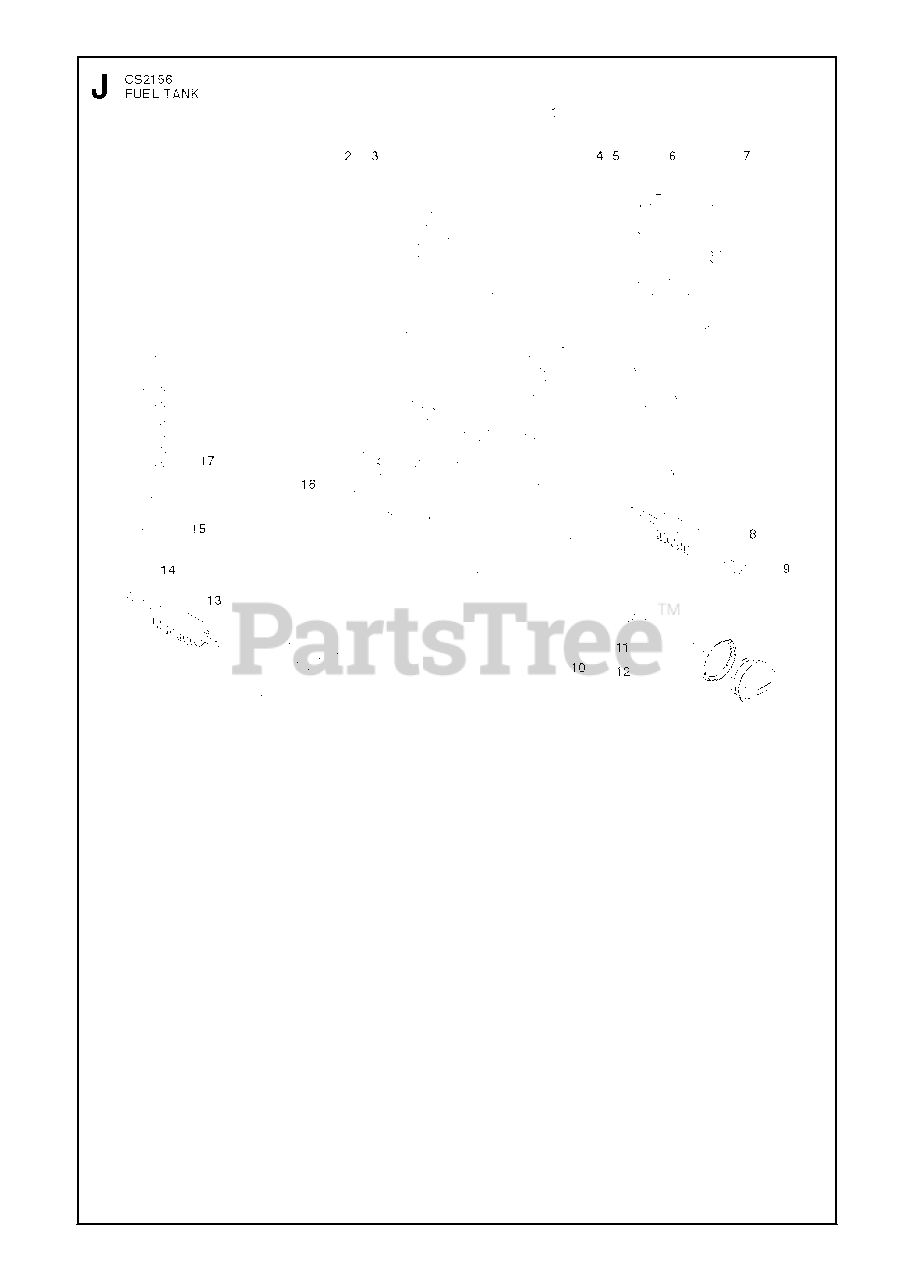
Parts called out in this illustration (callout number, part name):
2	FUEL TANK VENT
3	FUEL HOSE
4	PIN
5	THROTTLE TRIGGER
6	THROTTLE LOCK
7	SPRING
8	VIBRATION ABSORBER
10	TANK CAP
11	HOLDER
12	SEALING
15	FUEL FILTER
16	PROTECTOR
17	FUEL HOSE
